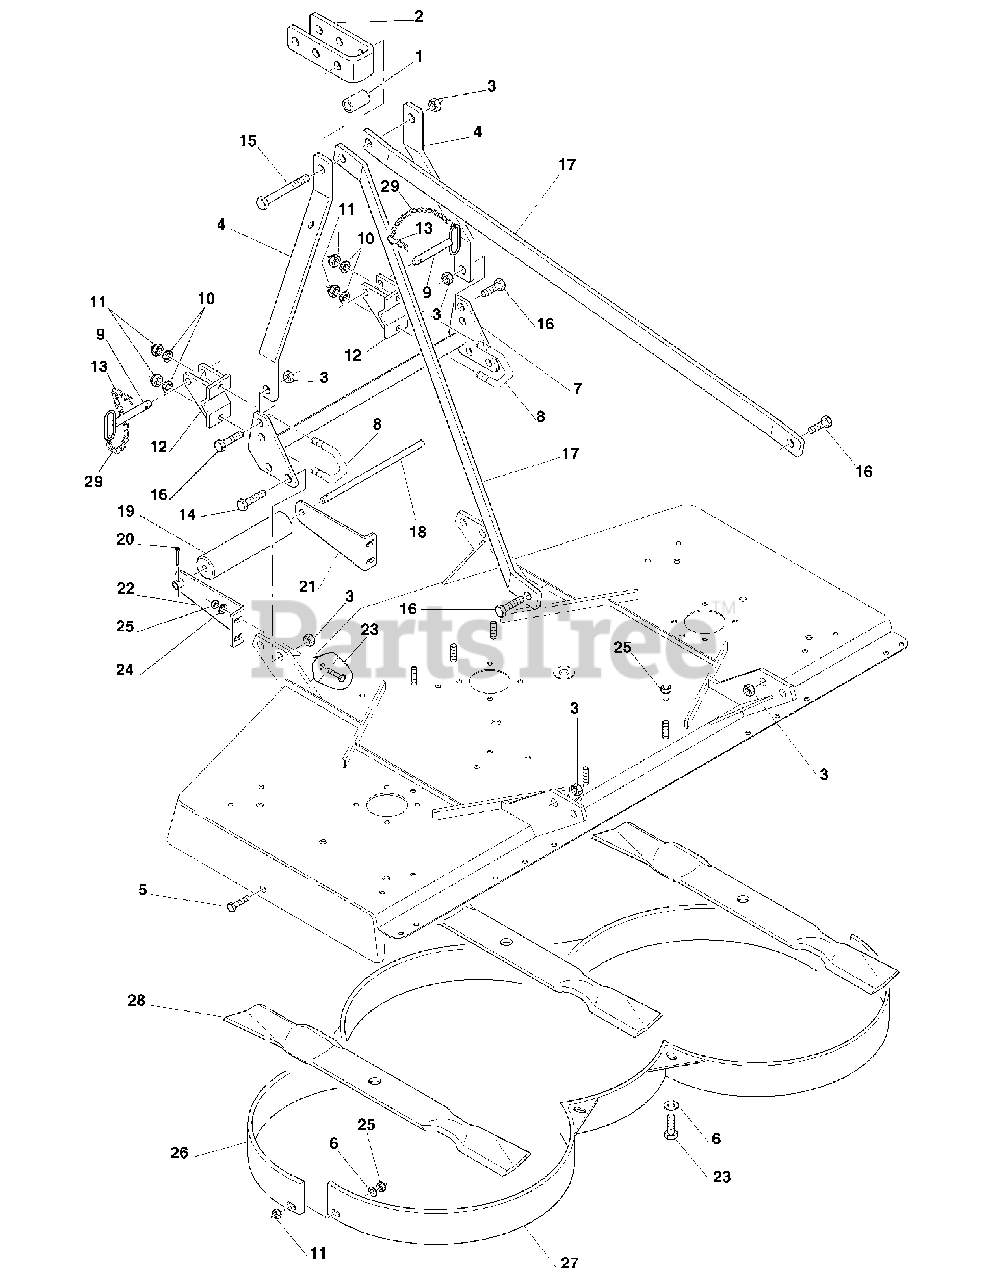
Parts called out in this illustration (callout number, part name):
2	Upper Plate
4	Top Hitch Support
5	Bolt TE 10 x 35
6	Flat Washer D.10
7	Tractor Hitch Support
10	Spring Washer D.12
11	Nut D. 12
12	Lower Hitch Arm
14	Bolt TE 16 x 45
15	Bolt TE 16 x 140
16	Bolt TE 16 x 40
17	Top Hitch Arm 48''
17	Top Hitch Arm 60''
17	Top Hitch Arm 72''
19	Front Roller
20	Cotter Pin D. 4x 50
21	Right Roller Support
22	Left Roller Support
23	Bolt TE 10 x 20
24	Flat Washer D.10
26	Baffling 48''
26	Baffling 60''
26	Baffling 72''
27	Baffling 48''
27	Baffling 60''
27	Baffling 72''
28	Mulching Blade 48''
28	Mulching Blade 60''
28	Mulching Blade 72''
